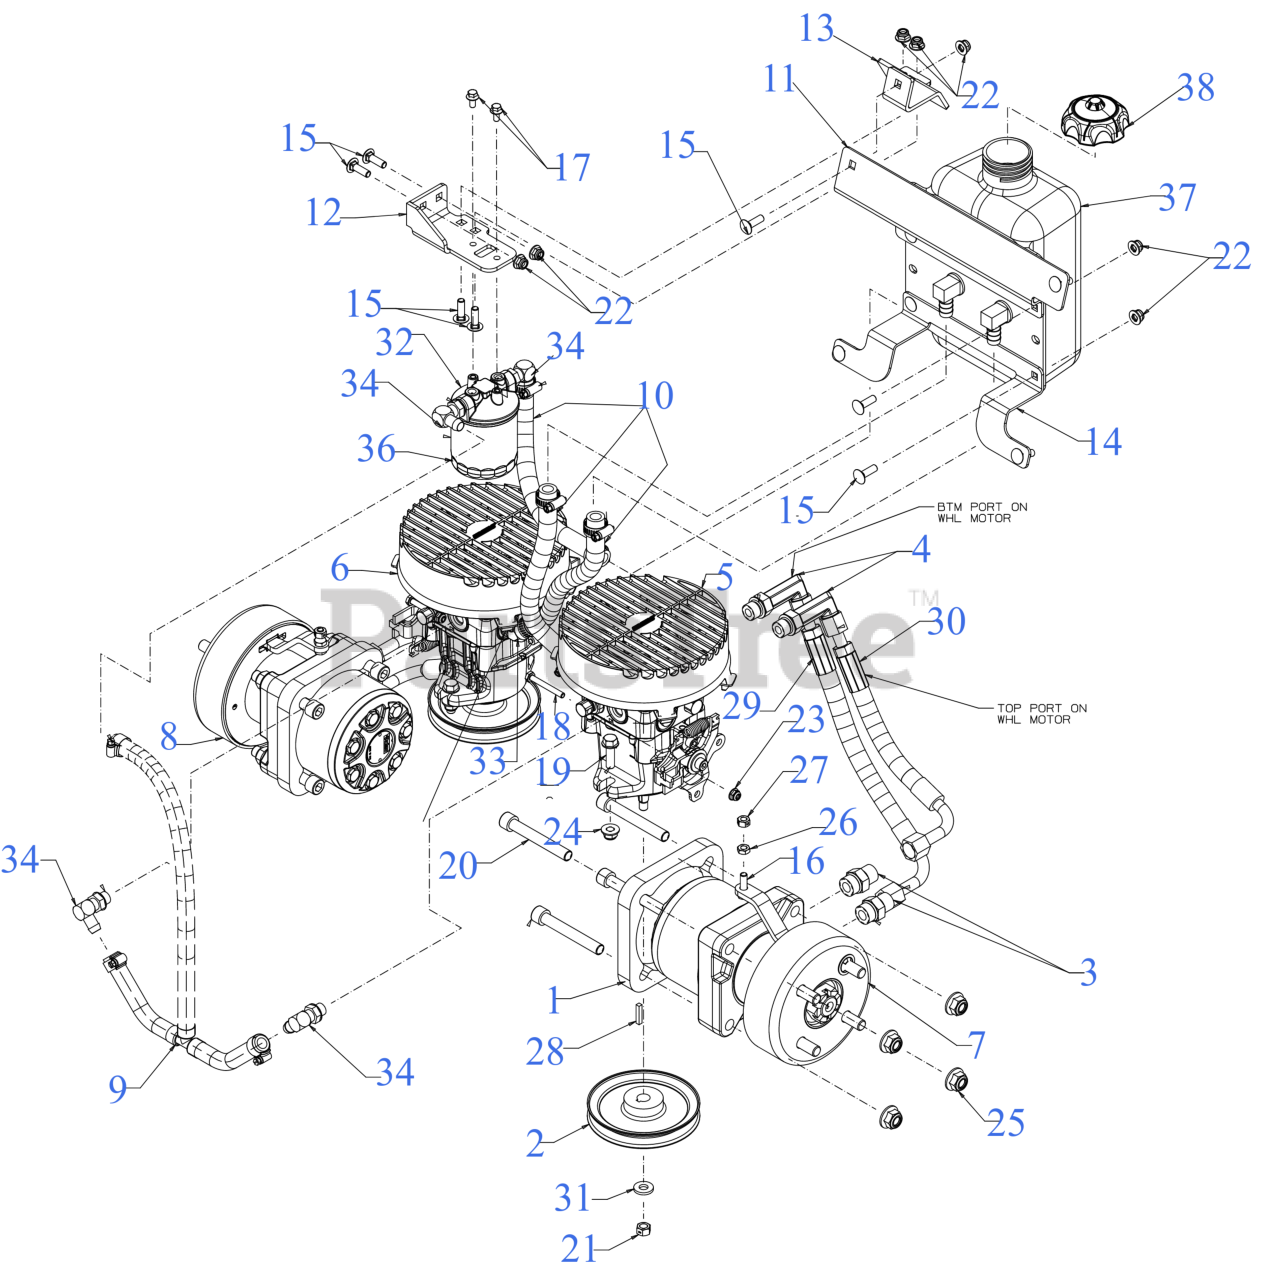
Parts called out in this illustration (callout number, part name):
1	WHEEL SPACER MOTOR
2	PULLEY-HYDRO PUMP
3	FITTING-ADAPTER 8
4	FITTING-ADAPTER 8
5	HYDRO PUMP (RH)
6	HYDRO PUMP (LH)
7	HYDRO MOTOR (RH)
8	HYDRO MOTOR (LH)
9	HYDRO DRAIN HOSE
10	HYDRO HOSE ASM 11"
11	OIL RESERVOIR BRACKET
12	FILTER MOUNT BRACKET
13	BRAKE CABLE MOUNT BRACKET
14	OIL RESERVOIR BRACKET (LOWER)
15	CARRIAGE BOLT 5/16-18 x 1.00
16	SCREW 5/16-18 x 1.0 GR5
17	SCREW 1/4-20 x .50 GR5
18	SCREW 1/4-20 x 2 GR5
19	SCREW 3/8-16 x 1.25 GR5
20	HEX CAP SCREW 1/2"-13x3.5
22	FLANGE LOCK NUT 5/16-18
23	FLANGE LOCK NUT
28	SQUARE KEY 3/16 x 1.00
29	HYDRO PUMP HOSE
30	HYDRO PUMP HOSE - TOP
31	FLAT WASHER
32	OIL FILTER ADAPTER
33	45 DEGREE FITTING (6 ORB X-8 BEAD)
34	ELBOW FITTING
36	HYDRAULIC FILTER
37	HYDRO OIL TANK (1 GAL)
38	HYDRO OIL TANK CAP
